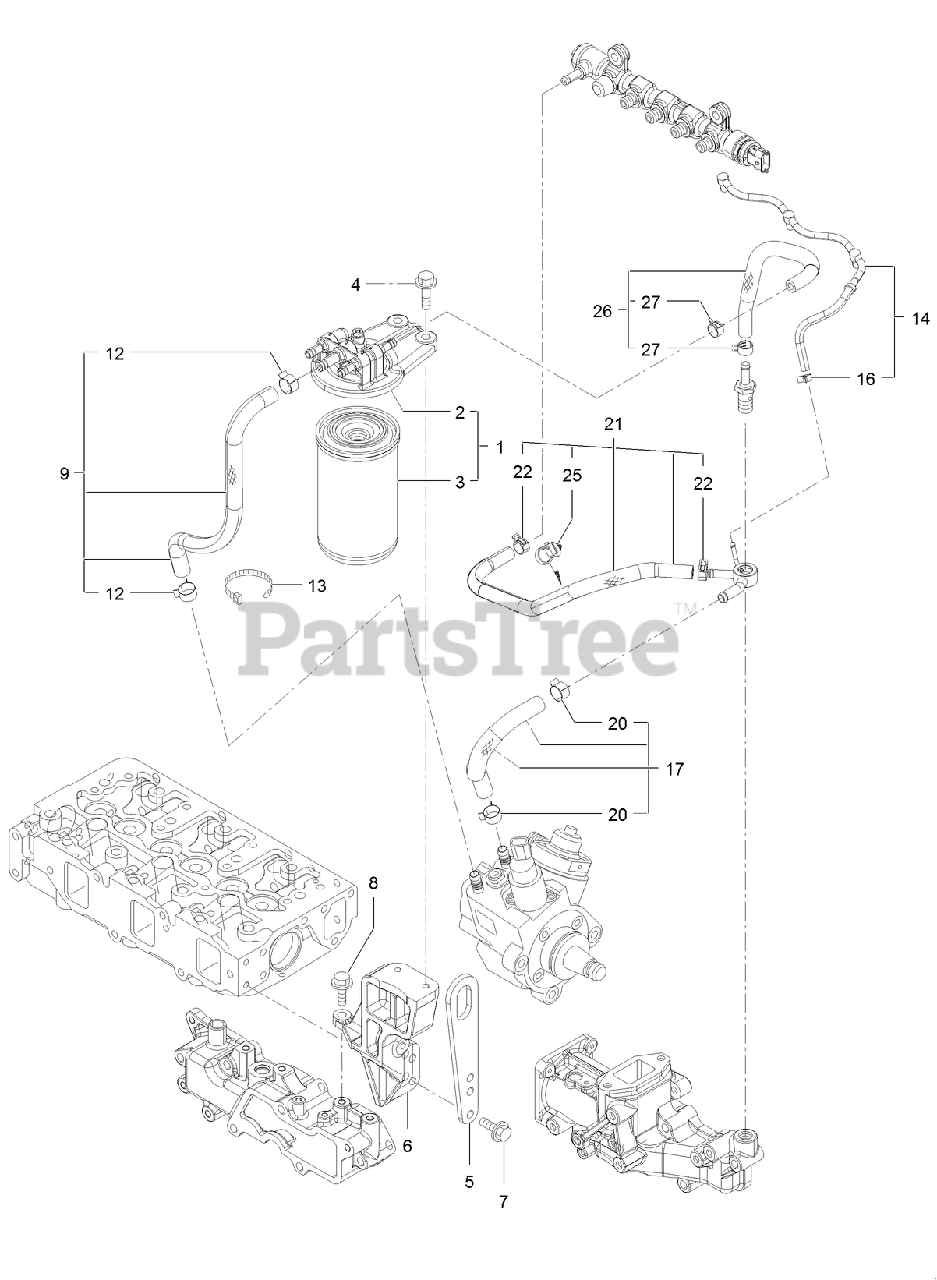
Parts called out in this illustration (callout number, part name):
1	FUEL/OIL FILTER ASM
2	FUEL/OIL FILTER BRACKET ASM
3	FILTER-FUEL/OIL
5	LIFTER
6	FILTER BRACKET ASM
9	FUEL PIPE ASM
12	CLAMP-HOSE
14	PIPE ASM-FO RETURN
16	CLAMP-HOSE
17	FUEL PIPE ASM
20	CLAMP-HOSE
21	FUEL PIPE ASM
22	CLIP-HOSE
25	BAND-CLIP
26	FUEL PIPE ASM
27	CLIP-HOSE
